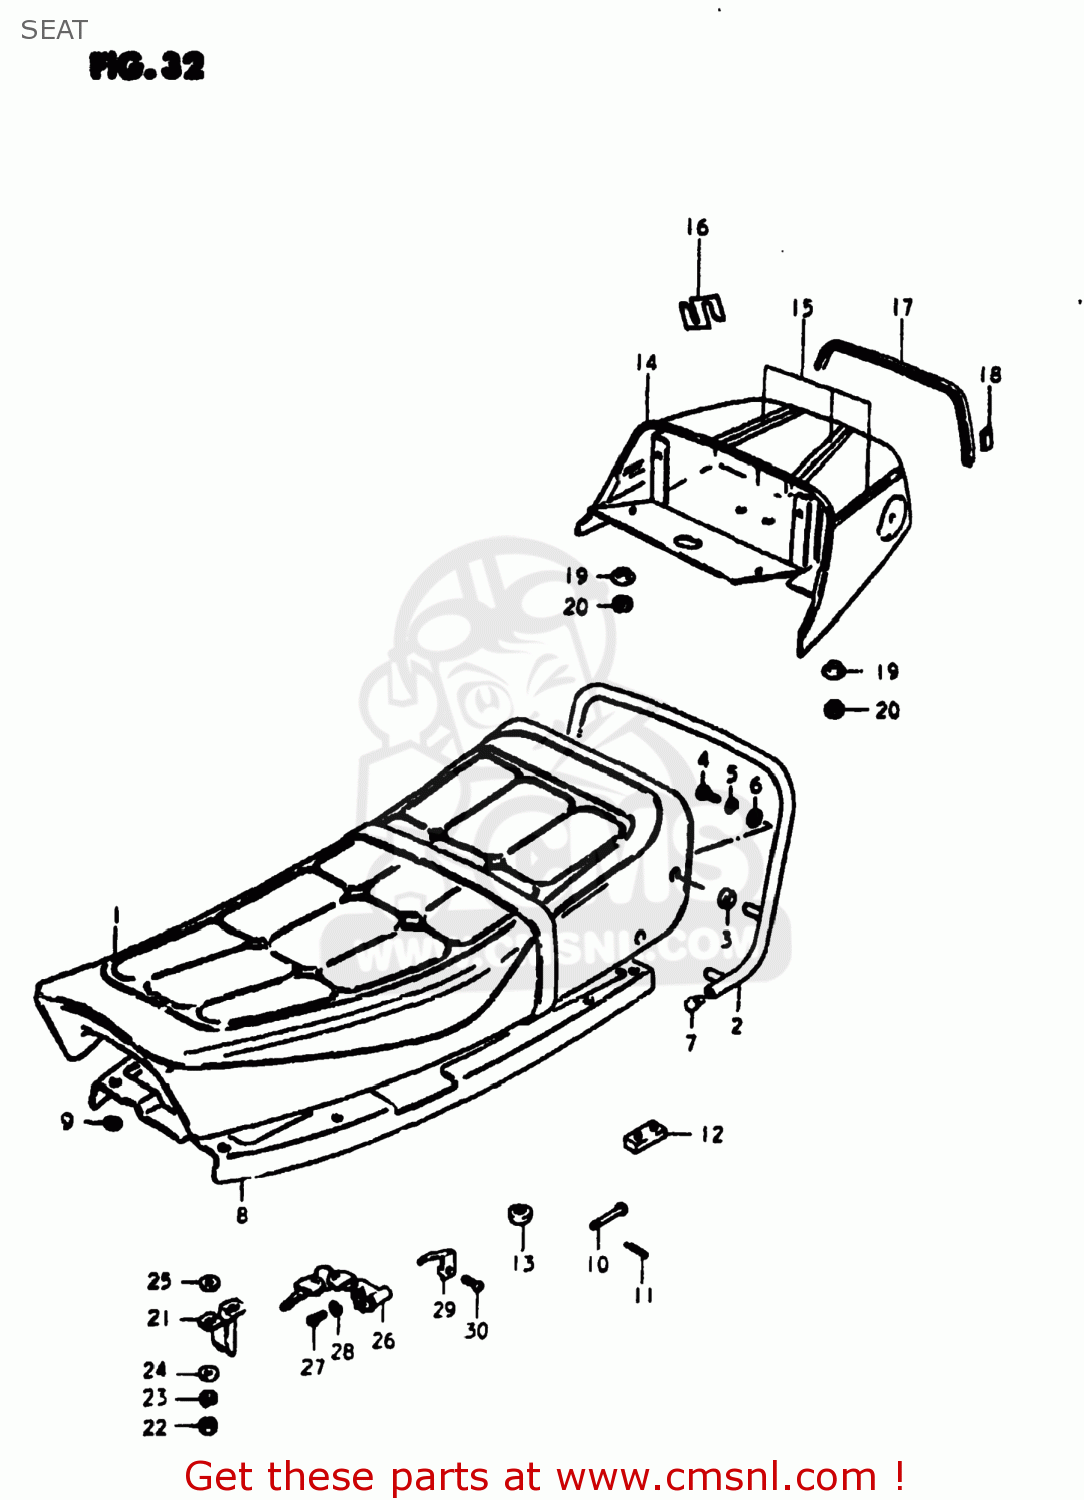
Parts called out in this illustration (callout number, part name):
1	SEAT ASSEMBLY
2	HANDLE,PILLION RIDER
3	CUSHION
4	BOLT
5	LOCK WASHER
6	WASHER
7	END,SHEET HANDLE
8	MOLDING,SEAT
9	NUT
10	PIN
11	PIN
12	CUSHION
13	CUSHION
14	COVER SET,SEAT TAIL
15	TAPE SET
16	EMBLEM,SEAT TAIL COVER
17	GROMMET
18	CLIP,SEAT TAIL COVER M
19	WASHER
20	NUT 6MM
21	STRIKER,SEAT LOCK
22	NUT
23	LOCK WASHER
24	WASHER
25	WASHER (6.5X20X1.2)
26	LOCK ASSY,SEAT
27	SCREW
28	LOCK WASHER
29	SPRING,HELMET HOLDER
30	SCREW
